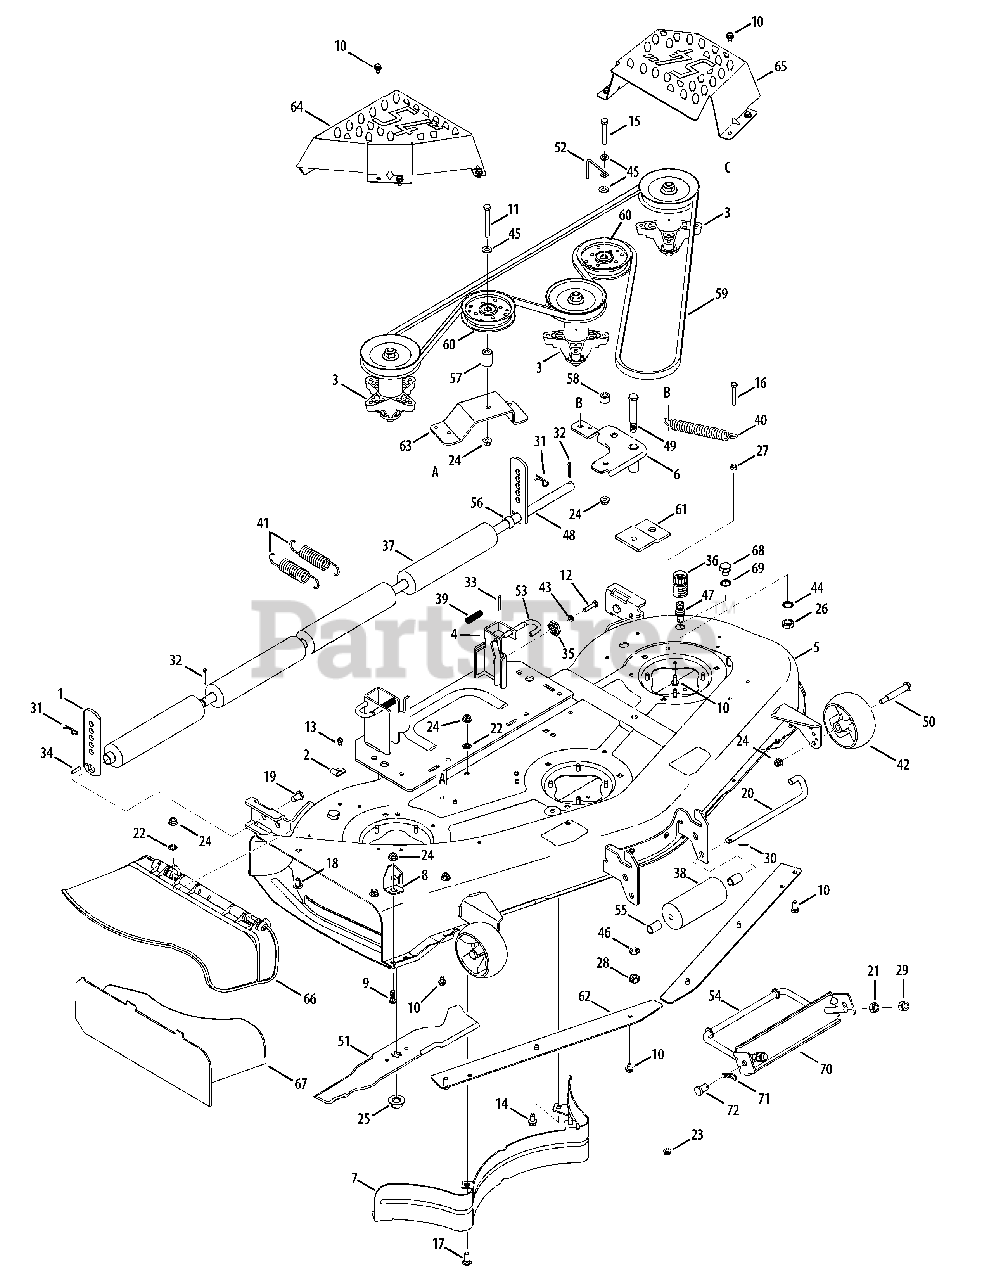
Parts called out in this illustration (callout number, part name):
1	Bracket, Height Adjustment
2	Retainer Hook Brkt.
3	Spindle Assembly
4	Deck Adjustment Bracket w/Weld Nut
5	54" Deck
7	RR Inner Baf fle
8	Chute Stop Deflector
9	Screw, 3/8-16 x 1.0
10	S-Tapp Scr 5/16-18 x .75
11	Screw, 3/8-16 x 3.0
12	Hex Bolt 5/16-18 x 1.25
13	Hex Wash S-Tapp Scr 1/4-20 x .50
14	Screw, 3/8-16 x 0.75
15	Screw, 3/8-16 x 2.5
16	Hex Hd Cap Scr. 5/16-18 x 2.0 Gr. 5
17	Carriage Bolt 3/8-16 x 1.0
18	Short Neck Carriage Bolt 3/8-16 x .75
19	Clevis Pin .50 Dia. x .78
20	Roller Pin .5" Dia x 10.06
21	Hex Nut 1/2-13
22	Push Nut 3/8
23	Flange Locknut 5/16-18 Gr. F, Ny lon
24	Flange Lock-Nut 3/8-16 Gr. F Ny lon
25	Hex Flange Nut 5/8-18
26	Hex Nut, M16-1.5
27	Hex Nut 5/16-18 hd. (Gr. 5)
28	Hex L-Nut 1/2-13
29	Hex L-Nut 1/2-13
30	Cotter Pin 3/32 x 1.0
31	Cotter Pin
33	Cotter Pin 1/8" Dia x 1.25
34	Spring Pin 1/4 Dia. x 1.0
35	Deck Adjustment Gear
36	Water Nozzle Adaptor
38	Front Roller
39	Compression Spring .531 OD x 1.75 Lg.
40	Extension Spring .94 Dia. x 6.74
41	Extension Spring 1.5 x 5.99
42	Deck Wheel 5.0
43	L-Wash 5/16 ID
44	Lockwasher 5/8
45	Flat Washer .406 x .875 x .059
46	Lockwasher
48	Shaft .75 x 47.12
49	Shoulder Screw
50	Shoulder Screw
52	Idler Belt Keeper Rod
53	Deck Release Pin
54	Deck Adjustment Rod
55	Spacer .55 ID x .75 OD
56	Spacer .82 ID x 1.0 OD x .53
57	Spacer .380 ID x .90 OD x 1.313
58	Spacer .385 ID x .88 OD x .64
59	V-Type Belt, B Section
60	Idler Poulie w/Flange 4.25 Dia
61	Bracket, Stabilizing
64	Spindle Cover RH
65	Spindle Cover LH
66	Chute Assembly
67	Mulching Plug
68	Plug Bolt, M16 x 1.5
69	Flat Washer .64 x 1.24 x .06
70	Front Deck Rod Adjustment Bracket
71	Hair pin Clip
72	Clevis Pin .50 x .78
